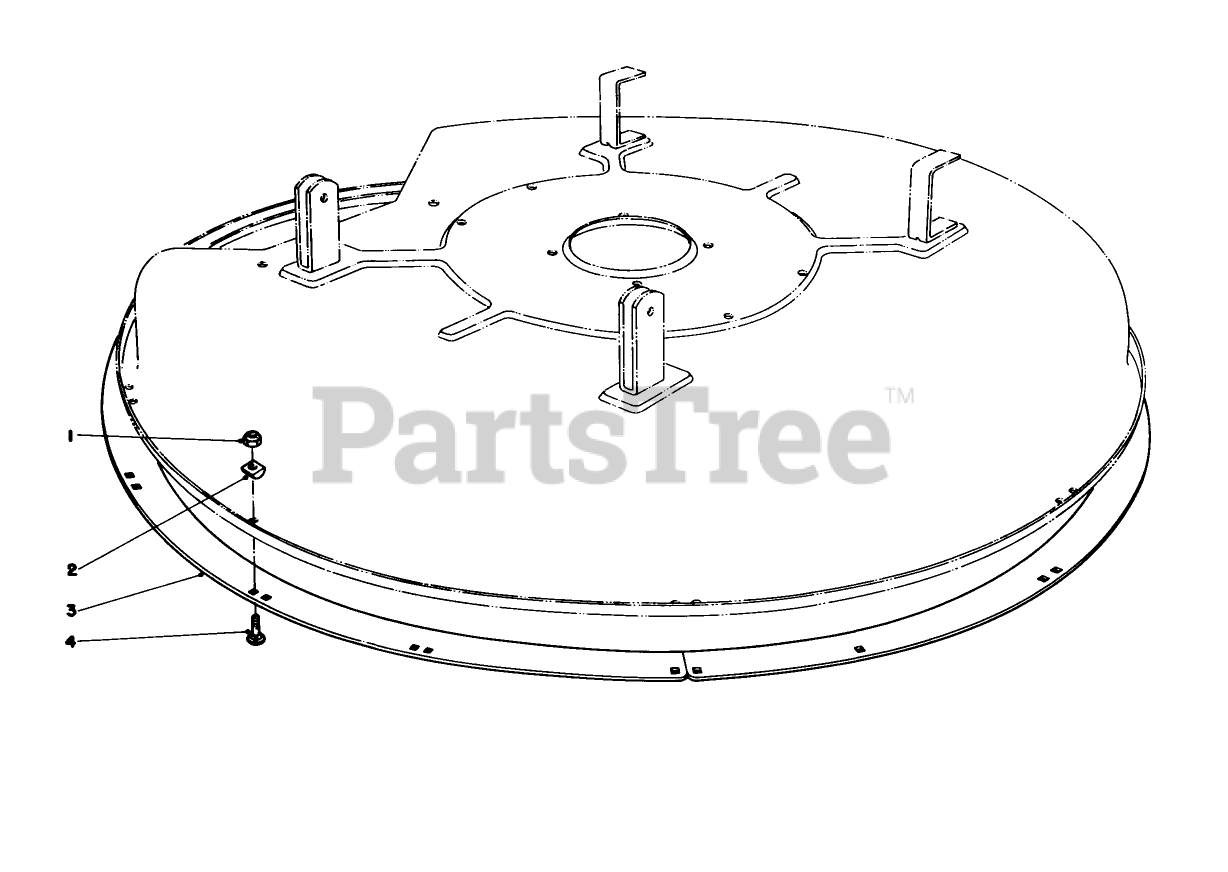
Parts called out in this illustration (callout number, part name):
1	NUT-LOCK, NI
3	DECK RING *B
4	BOLT-CARR
